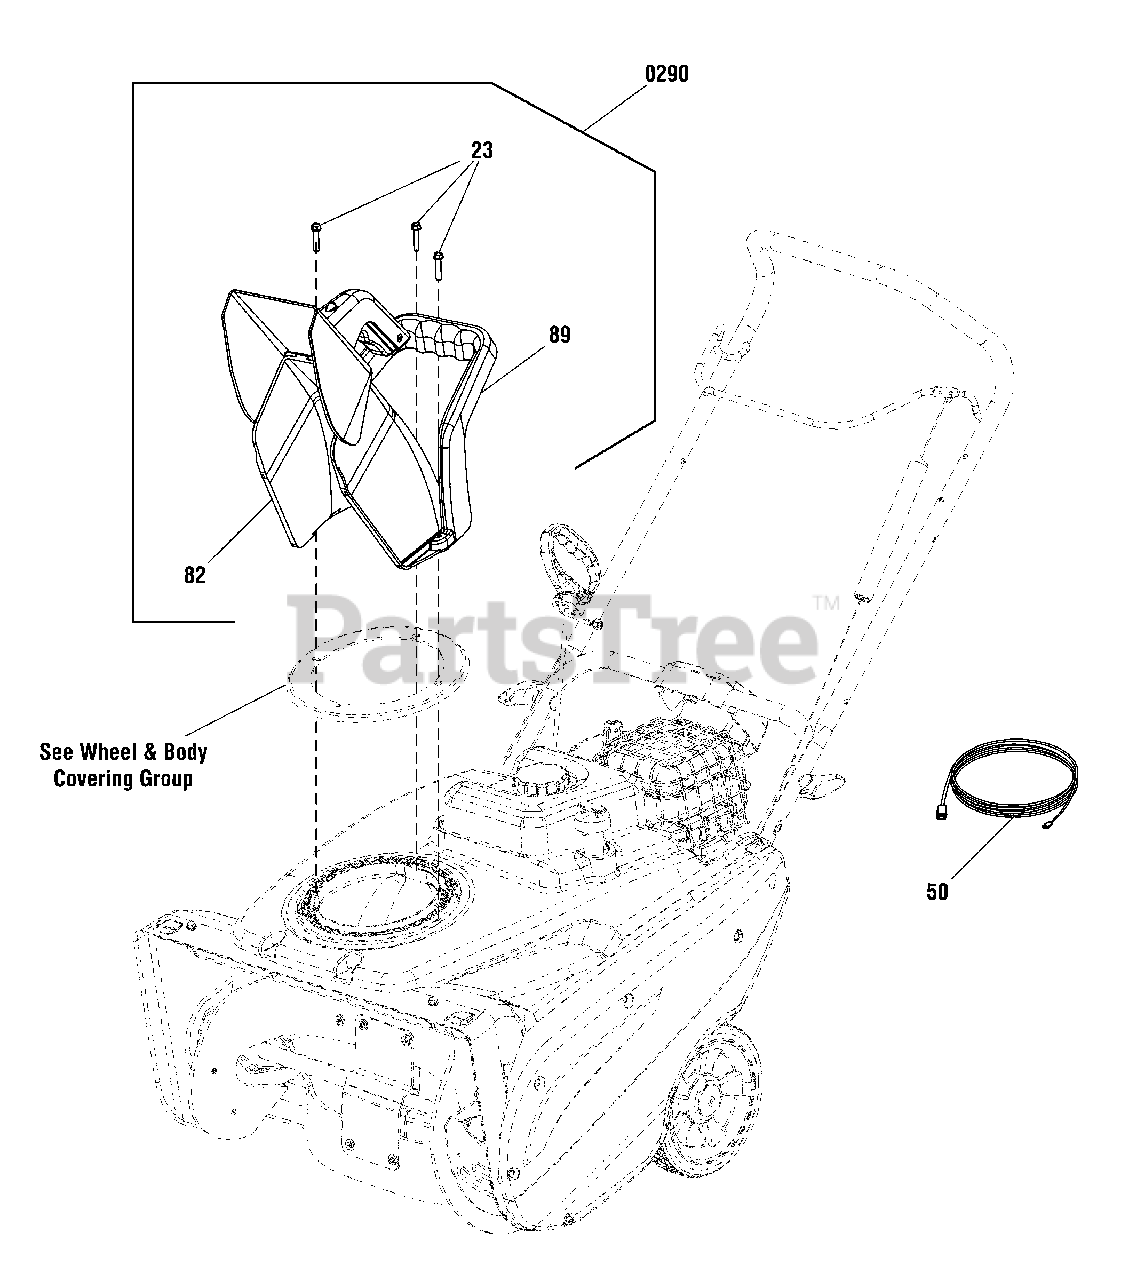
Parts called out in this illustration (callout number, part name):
23	*SCREW, Philips Hex Washer Head, 1/4-15x1-1/4
50	CORD, Electric
82	*CHUTE, Assembly, Quick Deflector
89	*HANDLE, Chute Rotation
0290	KIT, CHUTE ASSEMBLY
